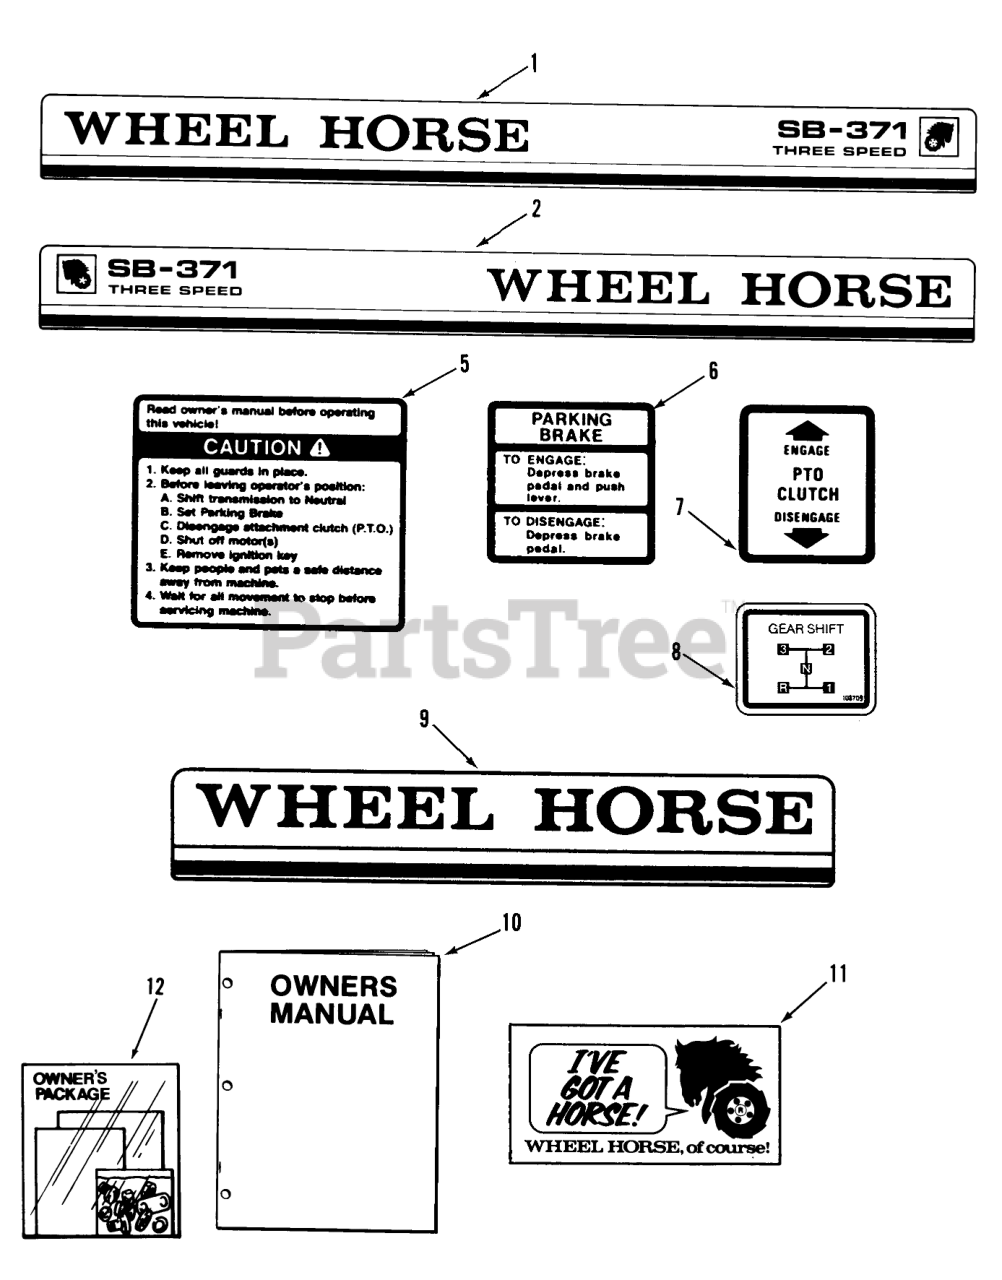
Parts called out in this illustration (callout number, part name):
1	Decal-Hood RH
2	Decal-Hood LH
5	DECAL-CAUTION
6	Decal Parking Brake
7	DECAL-PTO CLUTCH
8	DECAL-SHIFT
9	DECAL-REAR
10	Owner-s Manual
11	Decal-I-ve Got A Horse
12	New Tractor Loose Parts Completing Package
